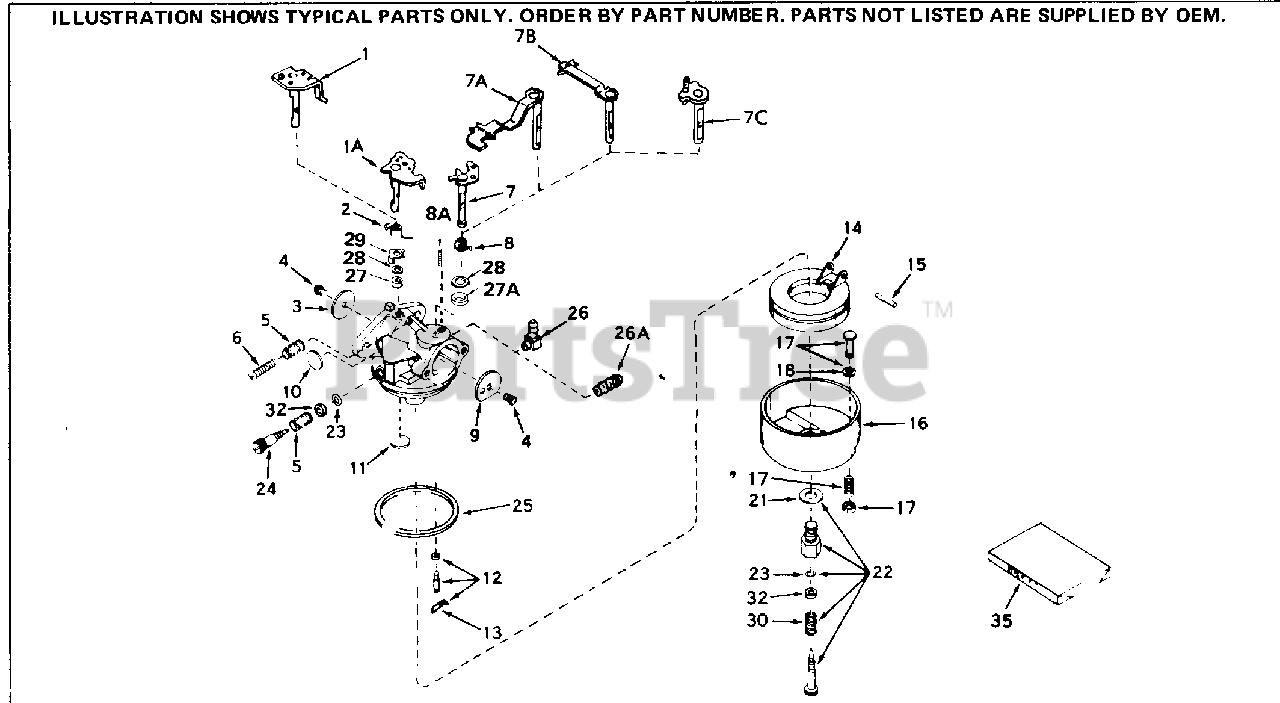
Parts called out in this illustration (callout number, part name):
1	"Shaft & Lever Assy., Throttle
2	Spring, Throttle return
3	Shutter, Throttle
4	Screw, Throttle & Choke shutter
5	Spring, Regulating screw.
6	Screw, Idle regulating
7	Shaft& LeverAssy.,Choke
8	Spring, Choke return
9	Shutter, Choke
10	Welch Plug
11	Welch Plug
12	Inlet Needle, Seat & Clip
13	Clip, Inlet needle
14	Float, Carburetor
15	Shaft, Float
16	Bowl & Drain Assy., Float
17	Plunger Assy. , Drain
18	Gasket, Drain plunger
21	Gasket, Bowl-to-body
22	Adjustment Screw Assy. , Main
23	"Oll Ring, Adjustment screw
24	Screw, idle adjustment
25	Gasket, Bowl-to-body
26	Fitting, Fuel inlet
27	Dust Seal
27A	Dust Seal
28	Dust Seal Washer
29	Dust Seal Retainer
30	Spring, Main adjustment screw .
35	Repair Kit
